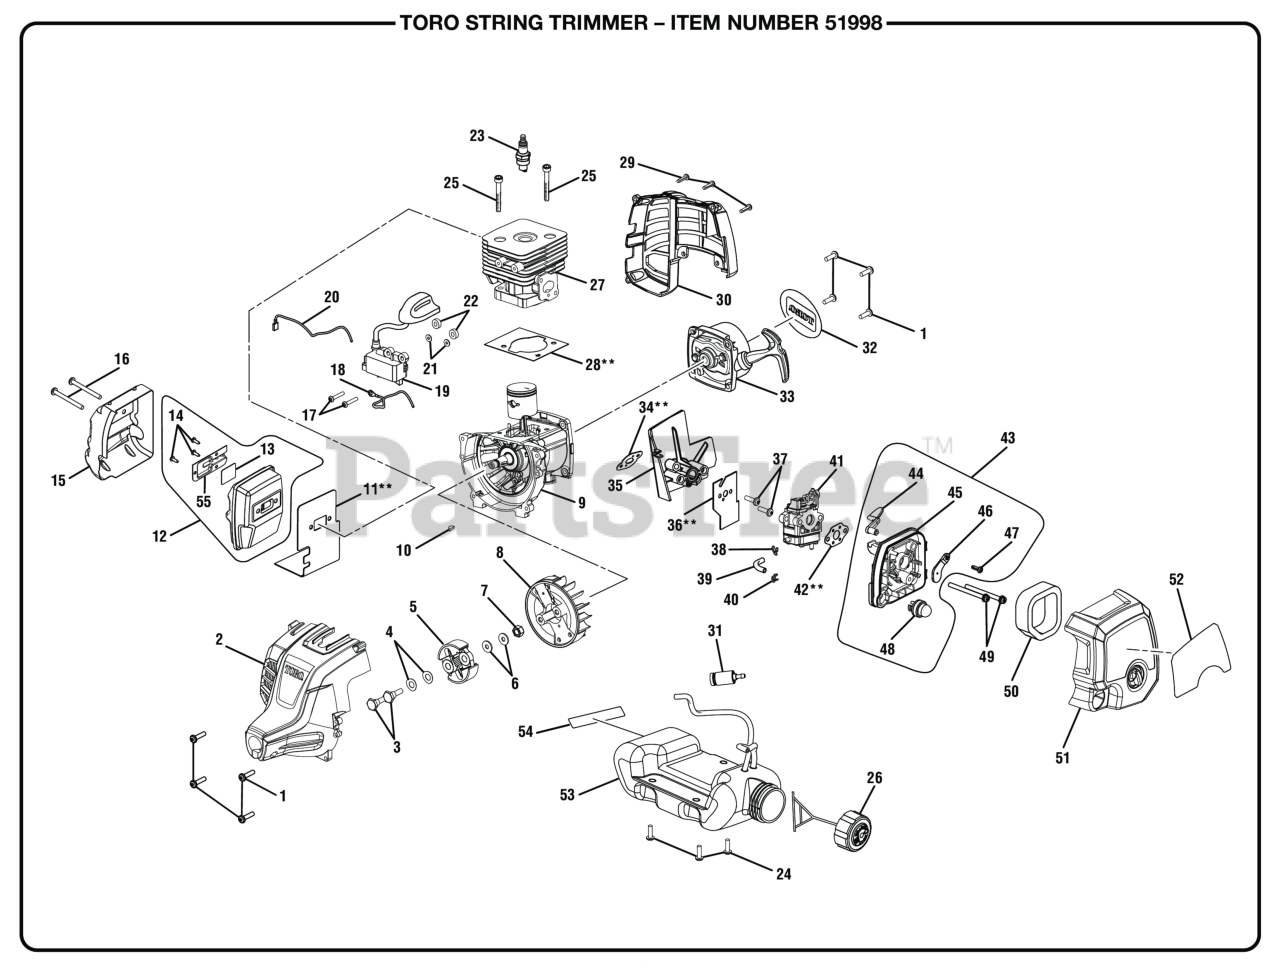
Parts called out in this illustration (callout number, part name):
1	Cap Screw w/Washer (M5 x 16 mm, T25 Torx Soc. Hd.)
2	Front Housing Assembly
3	Clutch Shoulder Bolt (M6 x 22.5 mm, Hex Hd.)
4	Washer (Curved)
5	Clutch Assembly
6	Washer (ID6 x OD15 x 1.2t)
7	Flange Nut (M8, Flywheel)
9	Crankcase Assembly.
10	WOODRUFF KEY (10 mm X 3 mm)
11	Muffler Gasket
12	Muffler Assembly (Inc. Key Nos. 3-4)
13	SCREEN
14	Screw (6-20 x 1/4 in., T20 Torx Pan Hd. S.T.)
15	HEAT SHIELD
16	Screw (M5 x 50 mm, Torx Slotted Recessed Pan Hd.)
17	Screw (M4 x 22 mm, T20 Torx Slotted Recessed Pan Hd.)
18	Lead Wire Assembly, Red
19	Coil Boot Assembly
20	Lead Wire Assembly, Black
21	Flat Washer (OD10 x ID42 x 1t)
22	Phenolic Spacer (Ignition Module)
23	SPARK PLUG (CHAMPION RCJ4)
24	Shoulder Screw w/Washer (M4 x 14 mm, T25 Torx Truss Hd.)
25	Screw (M5 x 22 mm, T25 Torx Soc. Hd.)
26	Fuel Cap Assembly
28	Gasket
29	Screw (M4 x 18 mm, T20 Torx Pan Hd. S.T.)
30	Rear Engine Housing
31	Fuel Filter
32	Logo Label (Rear)
33	Starter Recoil & Starter Cup Assembly
34	Heat Dam Insulator
36	Gasket
37	Screw w/Washers (M5 x 30 mm, T25 Torx Pan Hd.)
38	Clip-hose (Id 4.9)
39	Fuel Line (45 mm)
40	CLIP-HOSE (ID 4.9)
41	CARBURETOR ASSEMBLY
42	Carburetor Gasket
43	Filter Housing Assembly
44	CHOKE LEVER
45	CARBURETOR PLATE
46	Screw (M4 x 12 mm, T20 Torx Pan Hd. S.T.)
47	Screw (M4 x 12 mm, Slotted Recessed Pan Hd.)
48	Primer Bulb Assembly
49	Screw (M5 x 44 mm,T25 Torx Hd. Carburetor)
50	Air Filter (Element)
51	Airbox Cover Assembly w/Label
52	Starting Instructions Label
53	Fuel Tank and Cap Assembly
54	Warning Label (Combustion)
55	Trimmer Outlet
